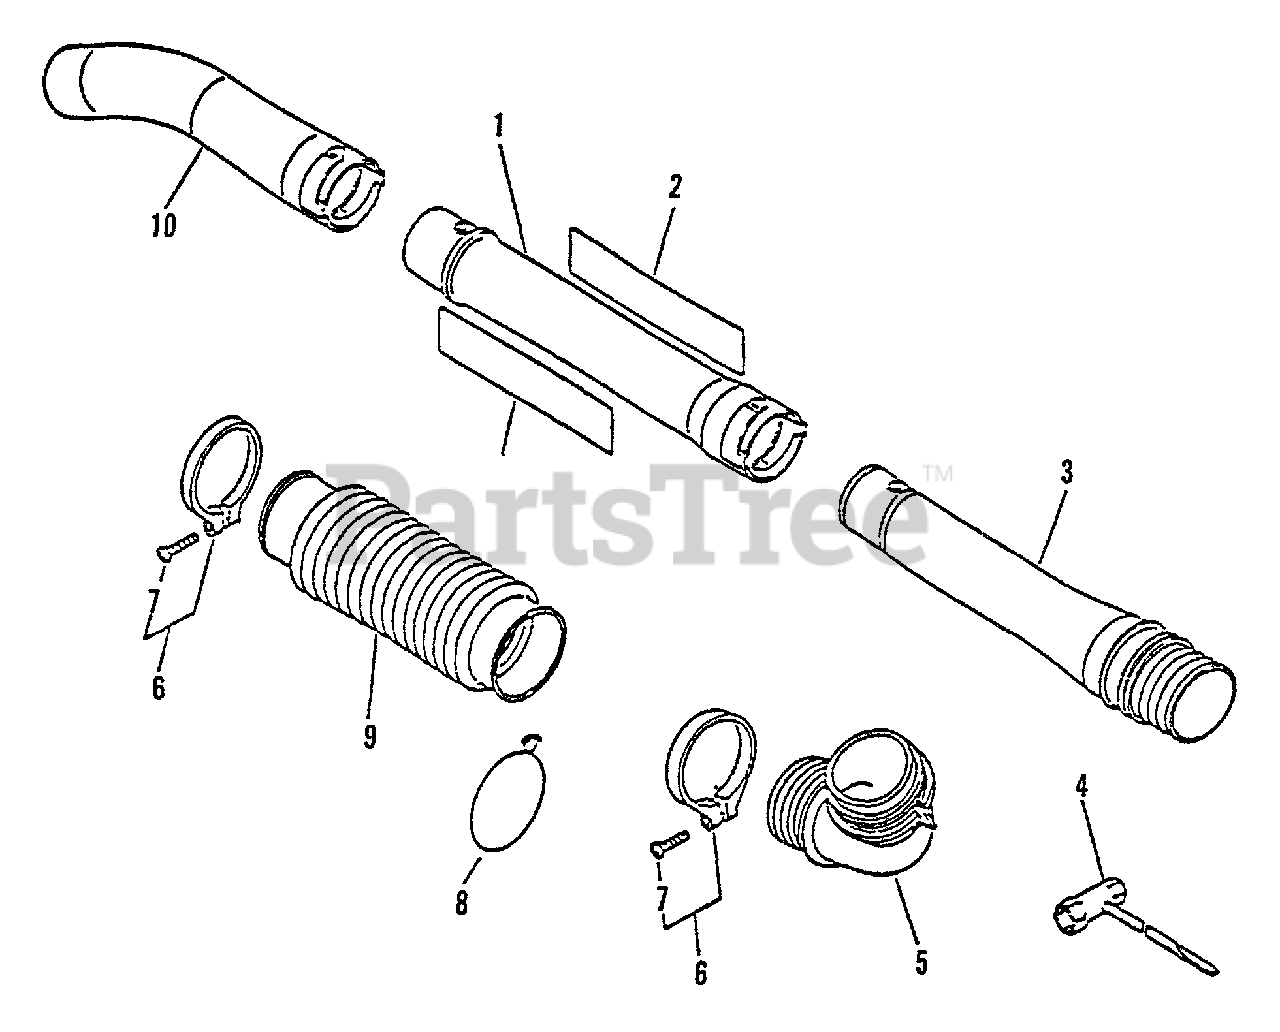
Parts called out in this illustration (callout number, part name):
1	TUBE, BLOWER - STRAIGHT
2	LABEL - LESCO
3	TUBE, SWIVEL
4	T-WRENCH 10×19 MM
5	PIPE
6	CLAMP KIT
7	SCREW 5×25
8	STRAP, TIE - LARGE
9	TUBE, FLEXIBLE
10	TUBE, BLOWER - CURVED
